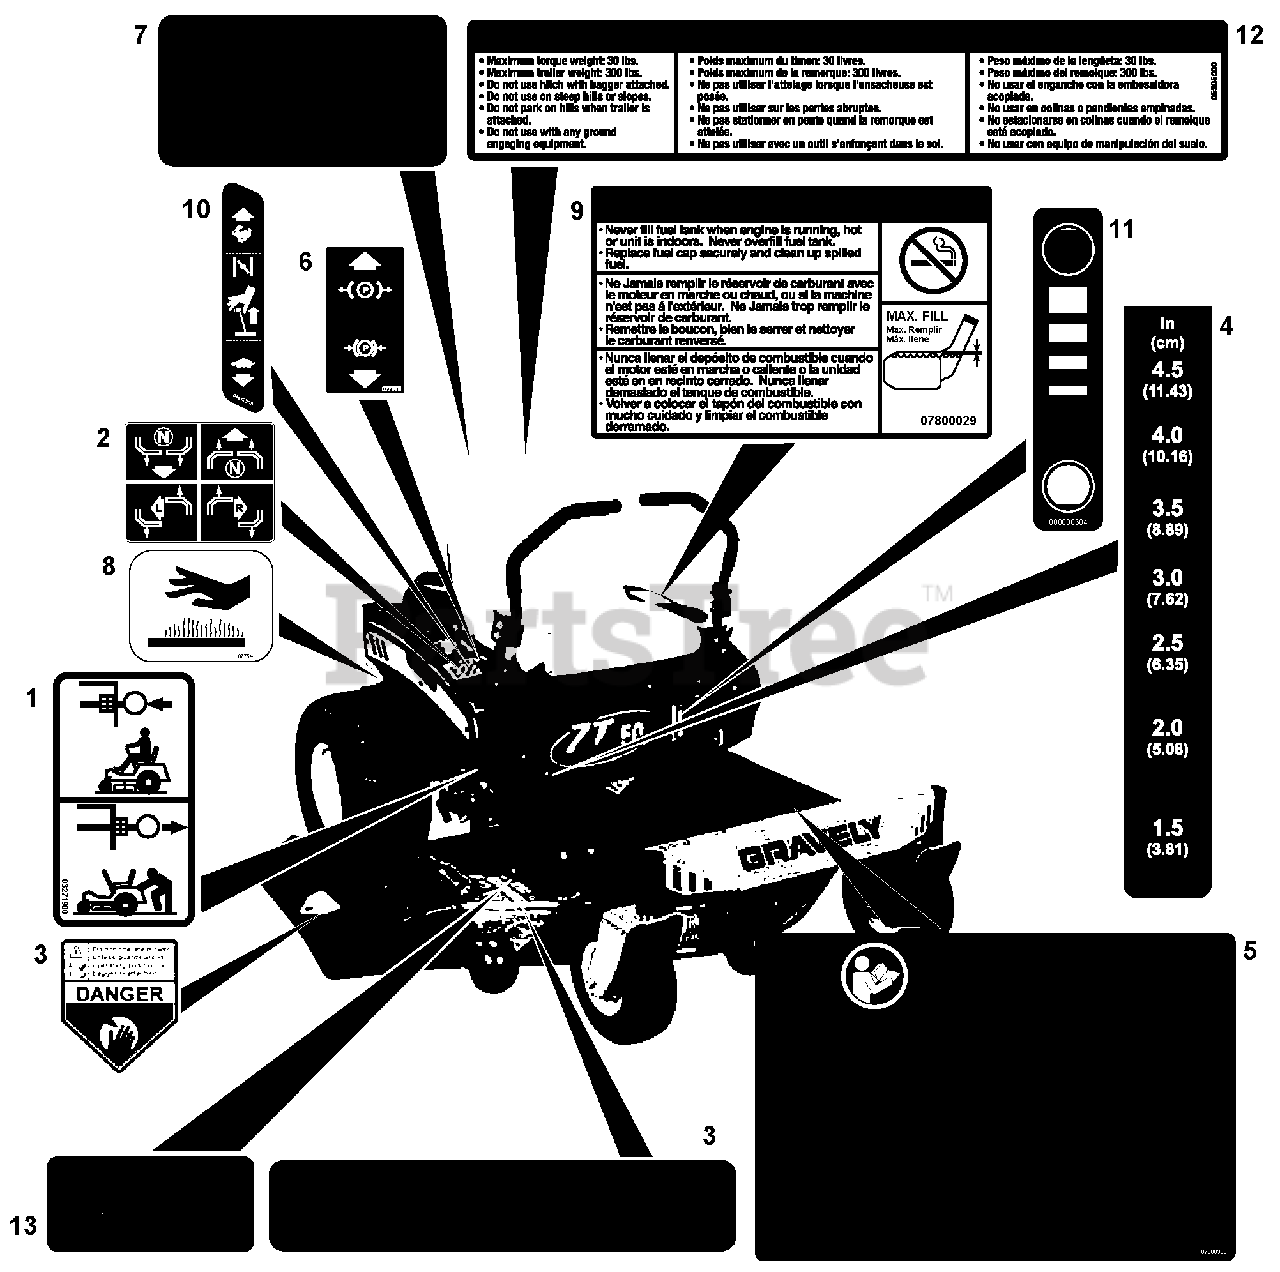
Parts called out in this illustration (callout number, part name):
1	Decal, Transmission Disconnect
2	Decal, Instructional Steering
3	Decal, Safety – Mower Deck
4	Decal, Cut Height
5	Decal, Safety – Main
6	Decal, Parking Brake Lever
7	Decal, Safety – Guarding
8	Decal, Hot Surface
9	Decal, Fuel Warning
10	Decal, Throttle Control (915146, 168)
11	Decal, Fuel Level
12	Decal, Trailer Hitch (915148, 150, 170)
13	Decal, Safety – Deck Guarding
